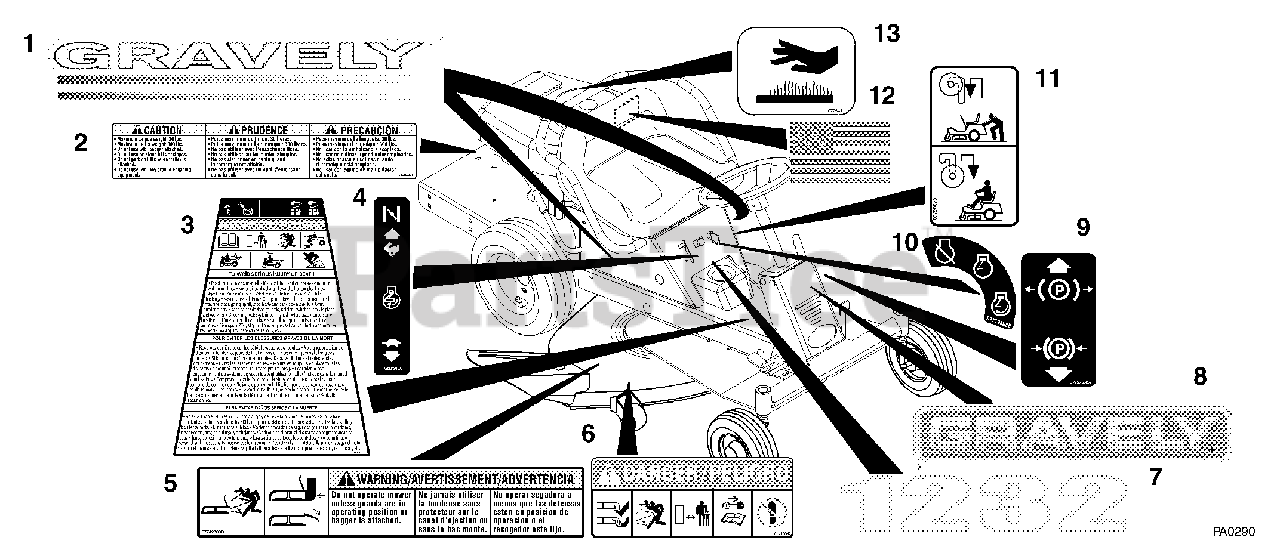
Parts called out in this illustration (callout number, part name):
1	Decal, Gravely ZT
2	Decal, Trailer Hitch
3	Decal, Rear Engine Rider Warning
4	Decal, Throttle
5	Decal, Warning
6	Decal, Mower Pan Danger
7	Decal, Rear Engine Rider Gravely 1232
8	Decal, Gravely
9	Decal, Parking Brake Lever
10	Decal, Ignition
11	Decal, Transmission Disconnect
12	Decal, American Flag
13	Decal, Hot Surface
